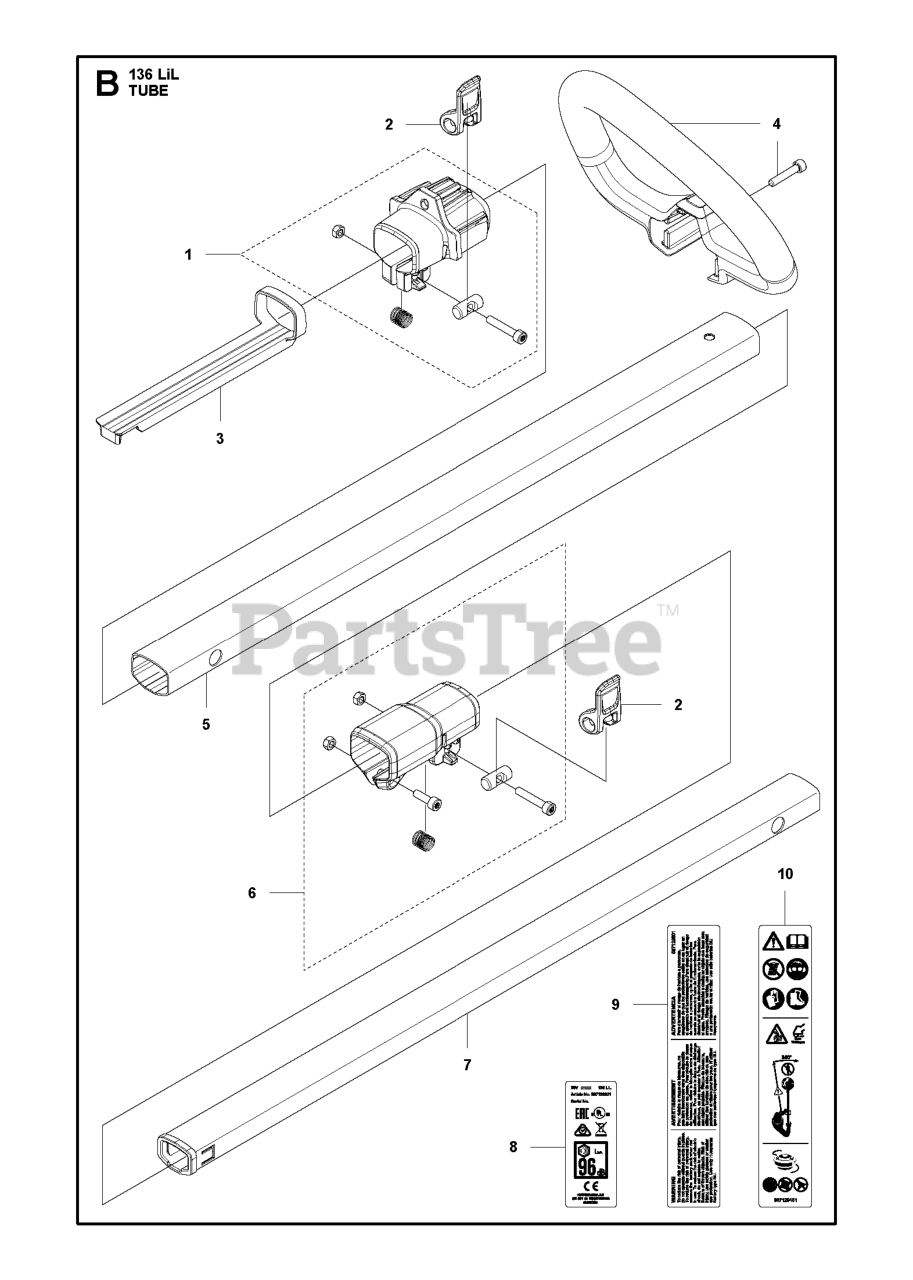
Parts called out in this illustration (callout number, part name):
1	COUPLING ,FRONT HANDLE ASSY
2	LEVER COUPLING
3	SPACER FRONT HANDLE
4	FRONT HANDLE
6	COUPLING ,TUBE COUPLING ASSY
7	TUBE SMALL TUBE ASSEMBLY
8	LABEL ,RATING
9	LABEL ,WARNING TEXT
